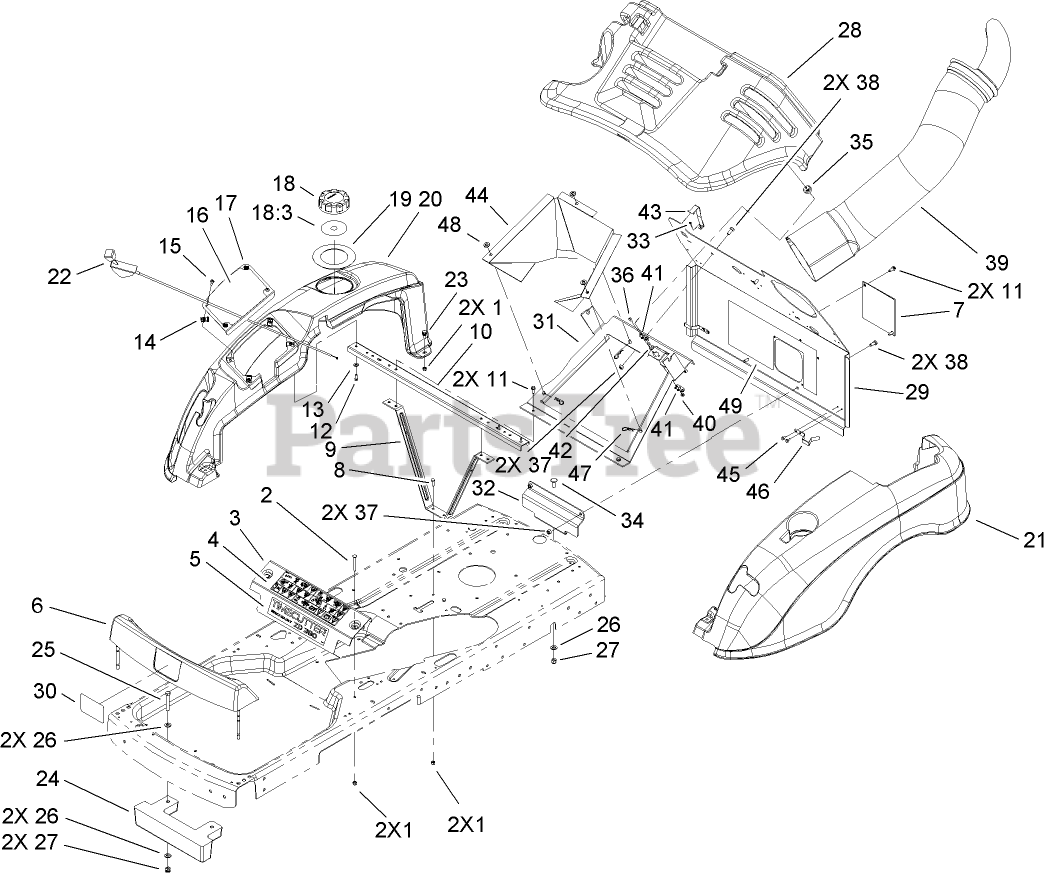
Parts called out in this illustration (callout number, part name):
1	NUT-LOCK, NI
2	SCREW-CARR
3	BRACKET-SUPPORT, FRONT
4	DECAL-DANGER
6	FOOTREST ASM
7	ACCESS DOOR ASM
8	SCREW-HH
9	BRACE ASM
10	CHANNEL-CROSS
11	SCREW-HWH, THREAD ROLL
12	SCREW-PLASTITE
13	WASHER-FLAT
15	SCREW-PRH
16	DECAL-CONTROL
17	PANEL-CONTROL
18	GAS CAP ASM
18:3	GASKET-CAP, GAS
19	SEAL-RUBBER
20	COVER-SIDE, RH
21	COVER-SIDE, LH
22	CABLE-THROTTLE
23	SCREW-SHOULDER
24	WEIGHT-BAGGER
25	SCREW-HH
26	WASHER-FLAT
27	NUT-LOCK, NI
28	COVER-ENGINE
29	SHIELD-HEAT, BAG
31	OFFSET HINGE ASM
32	HITCH-TRAILER
33	PIN-COTTER
34	SCREW-CARR
35	GROMMET
36	SCREW-HSBH
37	NUT-LOCK, NI
38	SCREW-HH
39	TUBE-DISCHARGE
40	NUT-LOCK, NI
42	PIN-HOOD
43	TAB-SWITCH
44	DUCT-FAN, ENGINE
45	SCREW-TAPTITE
46	CLIP-RETAINER, BAG
47	PIN-HAIR
48	WASHER-RUBBER
49	FOIL-HEAT SHIELD, BAG
